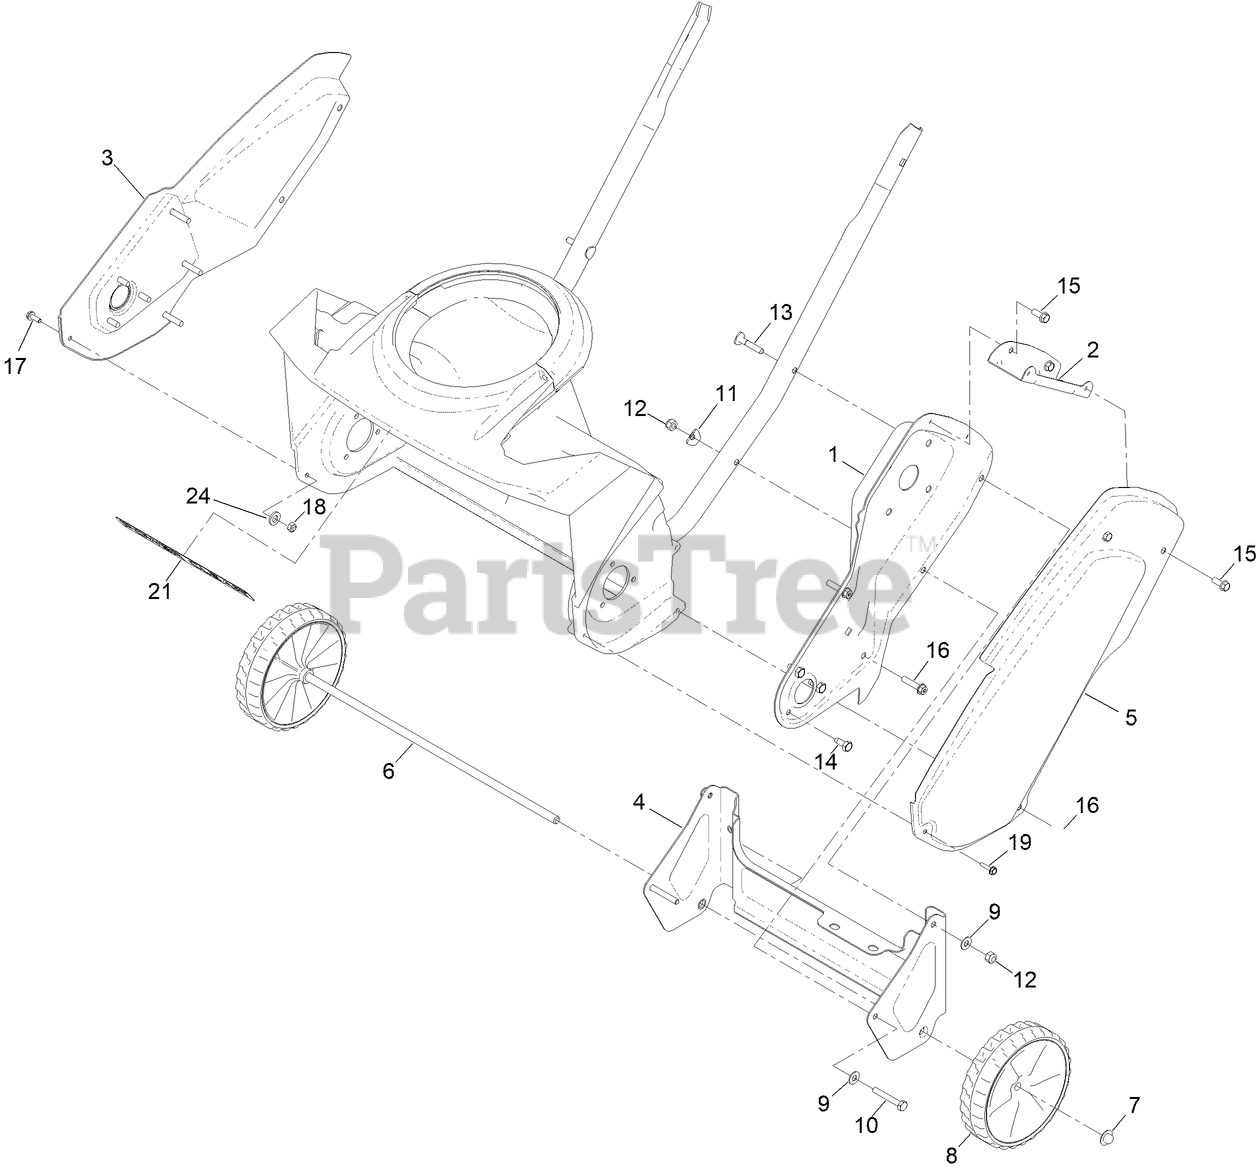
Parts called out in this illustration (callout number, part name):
1	SIDEPLATE-LH
2	BRACKET-COVER, BELT
3	SIDEPLATE-RH
4	BRACKET-WHEEL
5	COVER-BELT
7	NUT-PUSH
8	WHEEL ASM, 3/8" AXLE, 5.875 IN
9	WASHER-FLAT
10	SCREW-HH
11	WASHER
12	NUT-LOCK, NI
13	SCREW-HANDLE
14	SCREW-HH, TAPTITE
15	SCREW-HWH
16	SCREW-PLASTIC,HWH
17	SCREW-HWH
18	NUT-HEX
19	SCREW-PLASTITE, HWH
21	DECAL-FRONT
24	WASHER-PLAIN
